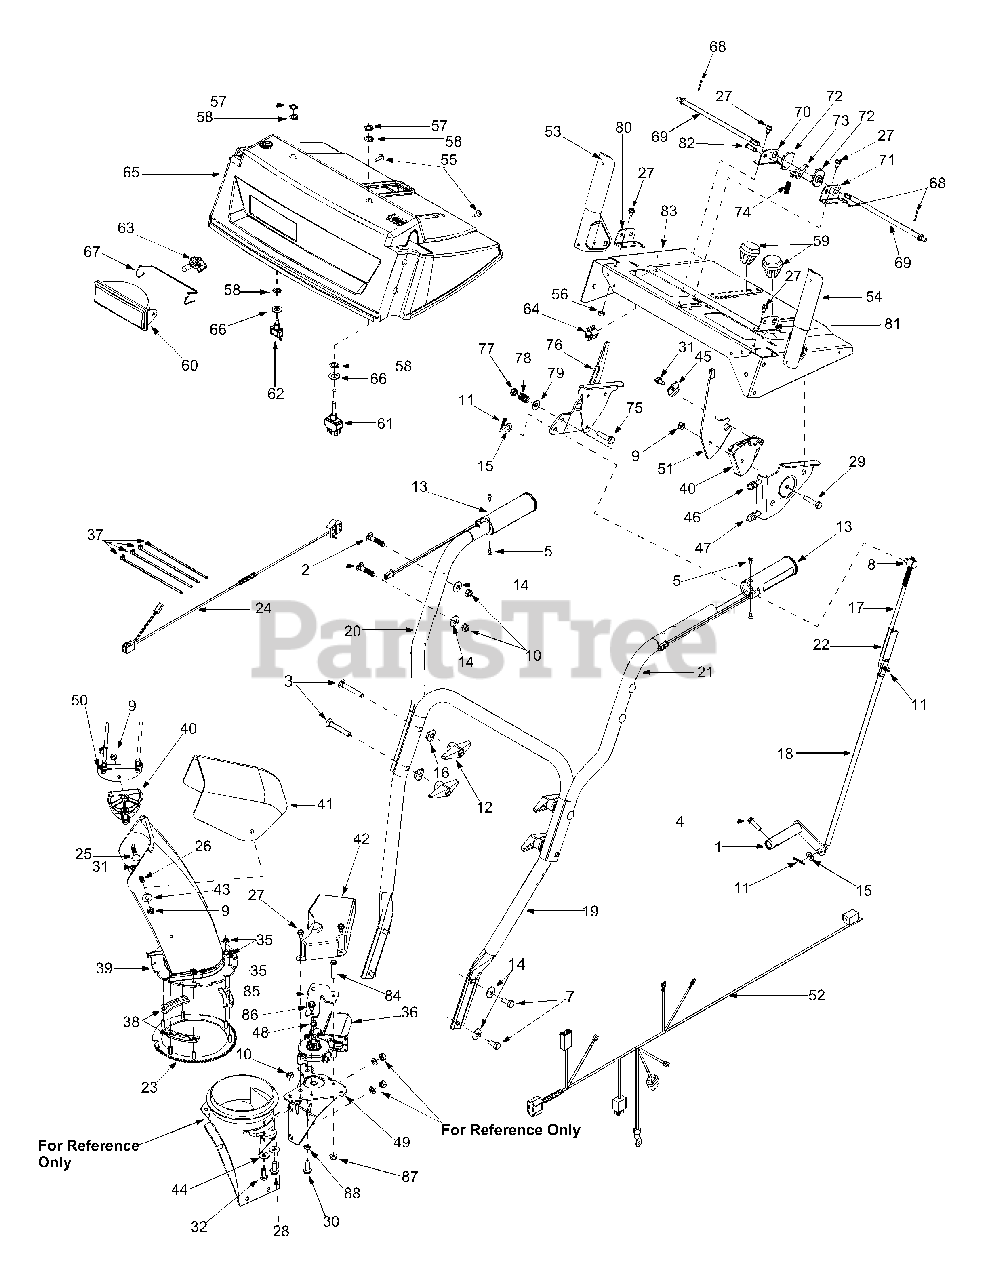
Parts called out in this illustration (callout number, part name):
1	Shift Arm Assembly
2	Carriage Bolt 5/16-18 x 1.5"
3	Carriage Bolt 5/16-18 x 2.25"
4	TT Screw 1/4-20 x 1"
5	C-Sunk Screw #10-16x 0.625"
7	Hex Screw 5/16-18 x .75"
8	Ferrule
9	Hex Lock Nut 5/16-18
10	Hex Nut 5/16-18
11	Cotter Pin
12	Handle Knob
13	Heated Grip
14	Belleville Washer
15	Flat Washer
16	Saddle Washer
17	Shift Rod: Upper
18	Shift Rod: Lower
23	Gear Assembly: Ring
24	Electric Harness: Lower
25	Carriage Bolt: 5/16-18 x 1.5"
26	Carriage Bolt: 5.16-18 x .750"
27	TT Screw: 1/4-20 x 0.5"
28	TT Screw: 5/16-18 x 1"
29	Hex Screw: 5/16-18 x 1.5"
30	Hex Washer Screw 5/16-18 x .875
31	Hex Screw AB:1/4-14 x 0.625"
32	Hex Screw: 5/16-18 x .75"
35	Hex Flange Lock Nut
36	Electric Motor: Chute Crank
37	Cable Tie
38	Chute Flange Keeper
39	Lower Chute
40	Cable Guide: Chute Tilt
41	Upper Chute
42	Motor Cover: Chute Rotation
43	5/16 Washer
44	Belleville Washer
45	Special Washer
46	Control Cable
48	Bushing
49	Motor Bracket
51	Handle: Chute Tilt
52	Harness Assembly: Upper
53	Handle Assembly RH
54	Handle Assembly LH
55	Special Hex Screw
56	Hex Sems Nut: 1/4-20
57	Hex Nut
58	Lock Ring: Toggle Switch
59	Shift Knob
60	Lamp Housing
61	Toggle Switch: Double Throw
62	Toggle Switch: Single Switch
63	Halogen Lamp: 50W, 12V
64	Mounting Clamp
65	Handle Panel
66	Flat Washer
67	Headlight Retainer
68	Cotter Pin: 3/32 x .75
69	Cam Rod
70	RH Handle Support Bracket
71	LH Handle Support Bracket
72	Cam Handle Lock
73	Handle Lock Pawl
74	Compression Spring: .36 x 1.0
75	Hex Cap Screw: 3/8-24 x 1.5
76	Shift Handle
77	Jam Nut, 3/8-24
78	Comp. Spring: .39 x .6 x .88
79	Bell Washer
80	RH Handle Support Bracket
82	Clevis Pin
84	Hex Cap Screw 1/4-20 x 1.5
85	Top Support Motor Bracket
86	Hex Washer Screw 1/4-20 1.5
87	Hex Flange Nut 1/4-20
88	Lock Washer 5/16
